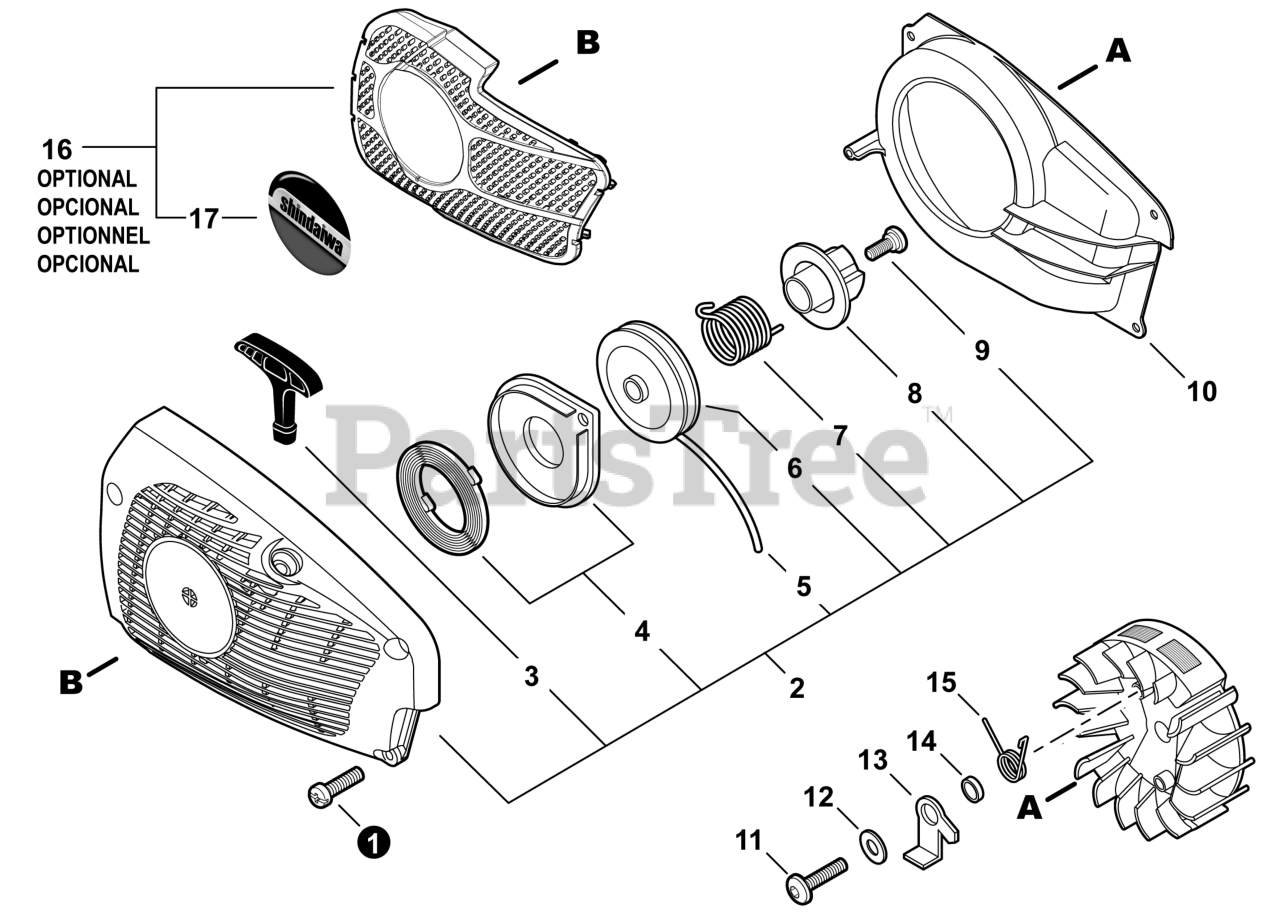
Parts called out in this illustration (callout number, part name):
1	BOLT, TORX 4x16
2	STARTER ASSY
3	GRIP, STARTER
4	SPRING KIT, RECOIL
5	ROPE, STARTER 3.5x900
6	REEL, ROPE
7	SPRING, RETURN
8	PLATE, CAM
9	SCREW
10	COVER, FAN
11	BOLT 5x14
12	WASHER 5.5x12x0.8
13	PAWL, STARTER
14	SPACER 5.2x8x2.1
15	SPRING, TORSION
16	SHIELD, DEBRIS
17	LABEL - STARTER - SHINDAIWA
